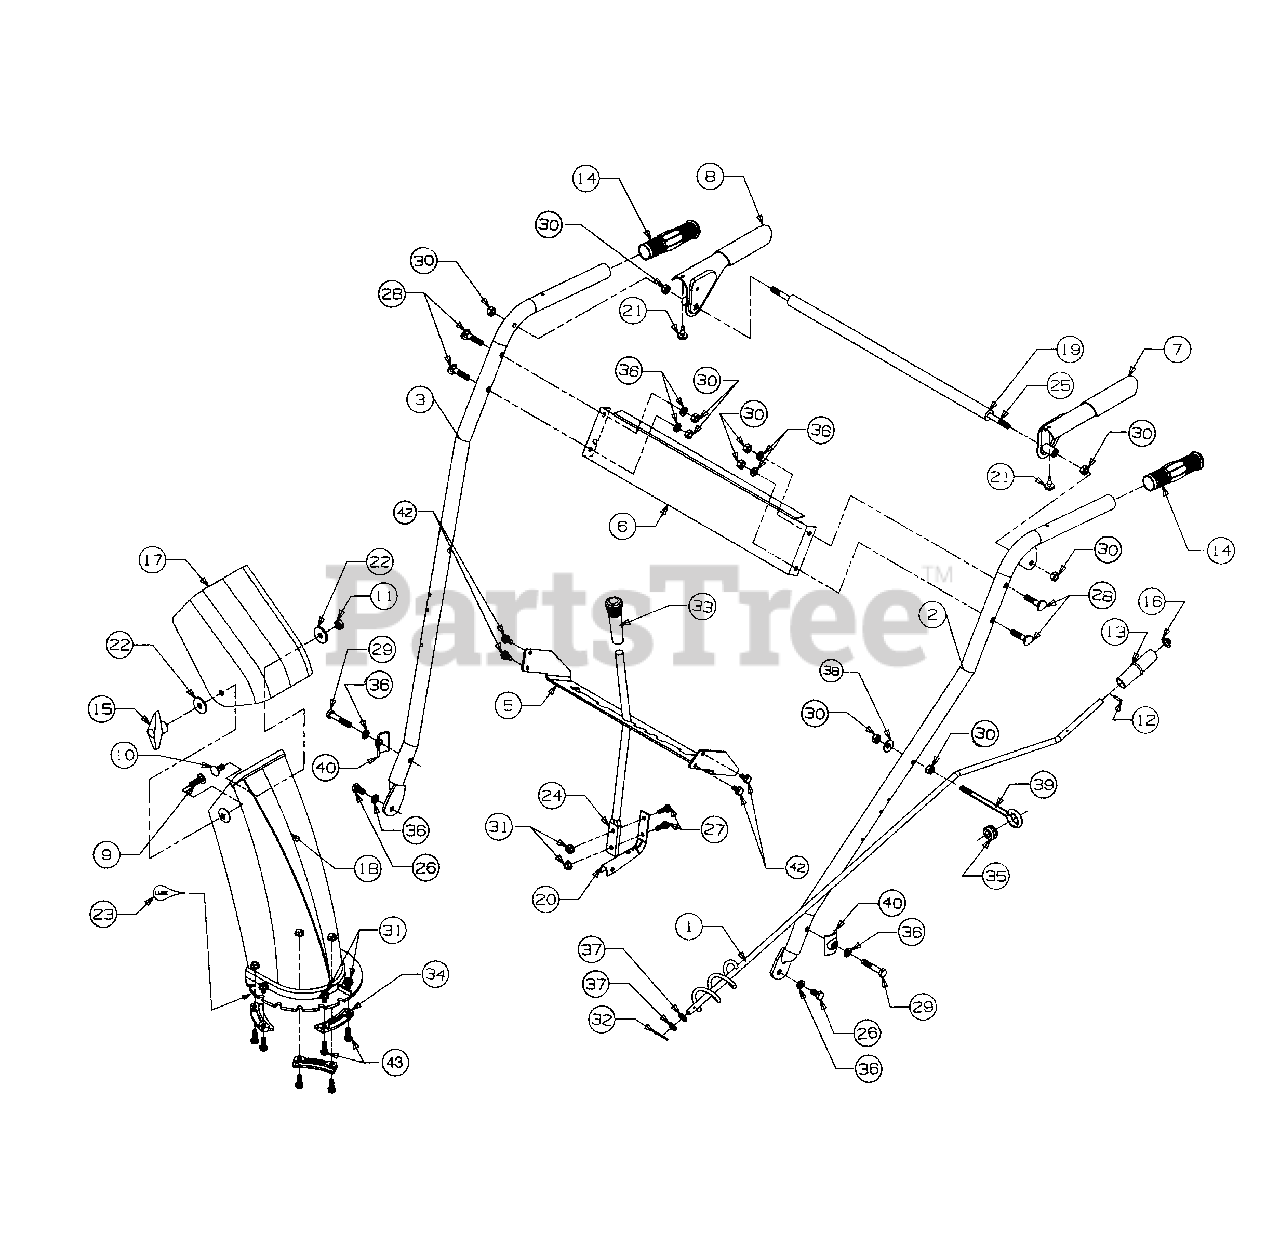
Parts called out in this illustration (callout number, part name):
1	Crank-Chute
8	Lever-Clutch-R.H.
9	Screw-Carriage
10	Screw-Carriage
11	Nut-Lock
12	Pin-Roll
13	Knob-Chute Crank
16	Cap-Push
17	Chute-Upper
18	Chute-Lower
19	Tube-Pivot Rod Cover
20	Spring-Shift Lever
21	Bumper
22	Washer
23	Grease
25	Rod-Pivot
26	Screw
27	Screw
28	Screw
29	Screw
30	Nut-Hex
31	Nut-Hex Flange
32	Pin-Cotter
33	Grip-Shift Lever
34	Keeper-Chute
35	Grommet
36	Washer-Lock
37	Washer-Flat
38	Washer-Bell
39	Eyebolt
40	Tab-Handle
42	Screw
43	Screw
